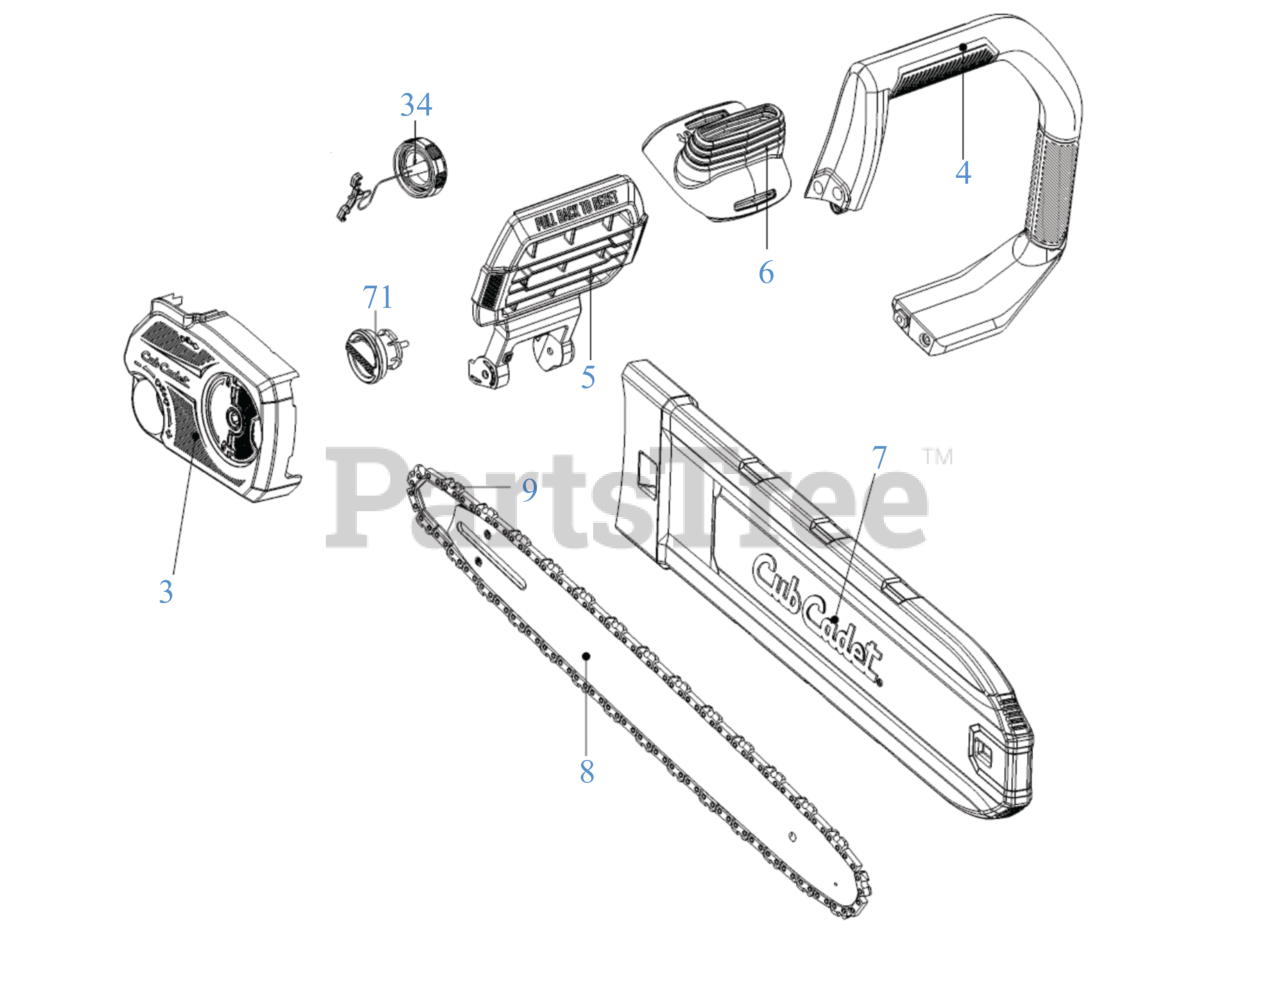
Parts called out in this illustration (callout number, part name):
3	CHAIN COVER
6	RUBBER DUST FLAP
8	Cub Cadet 16" CHAINSAW BAR
9	Cub Cadet 16" CHAIN (3/8 .043 GAUGE FILE 5/32)
71	CHAIN TENSIONER KNOB
